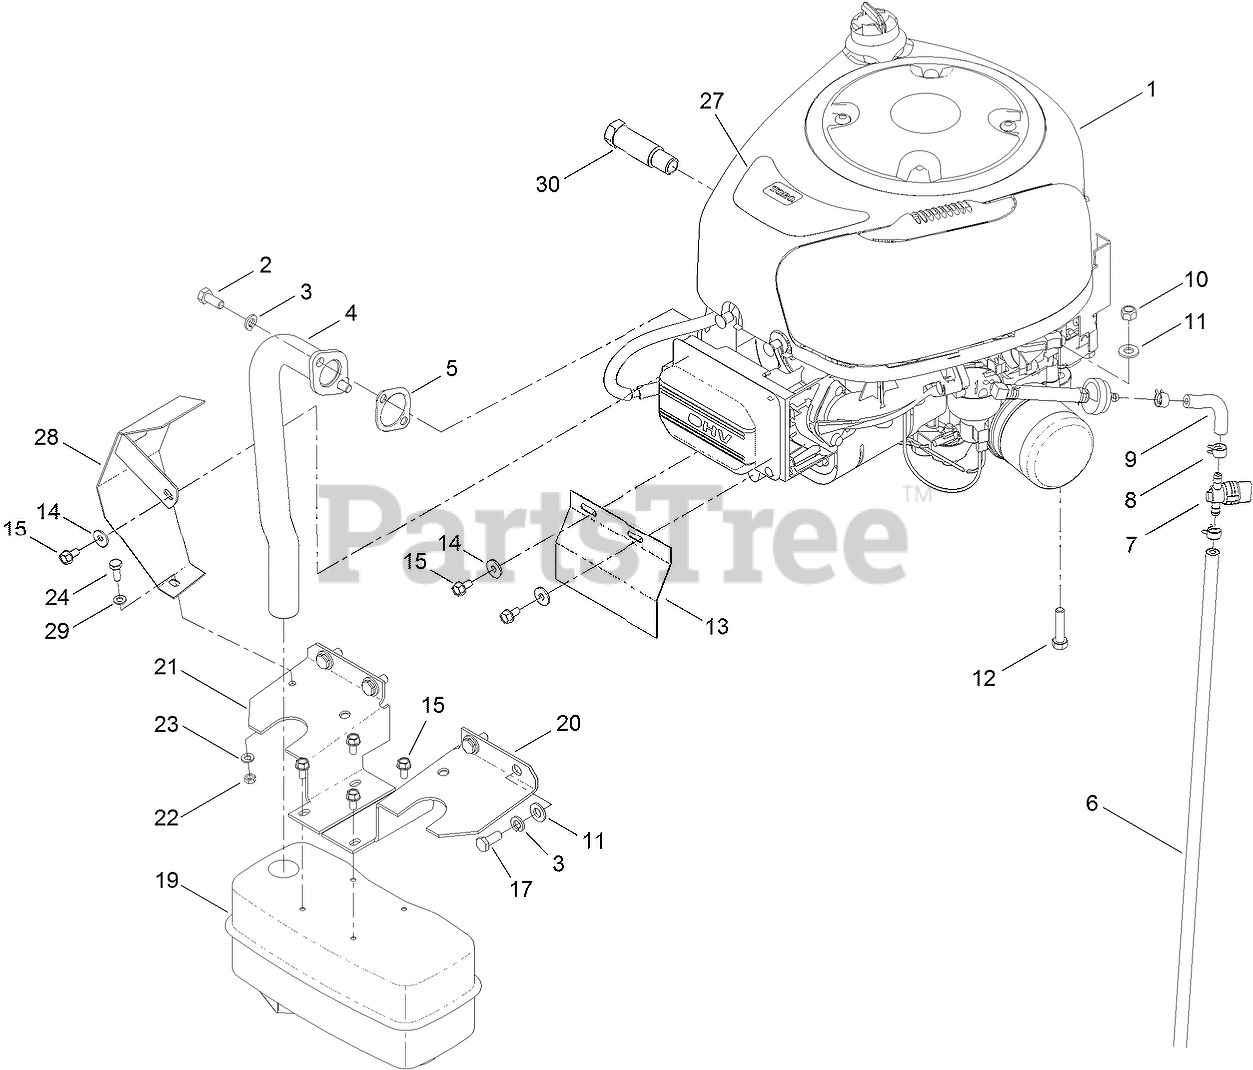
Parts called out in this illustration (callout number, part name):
2	SCREW-HH
3	WASHER-LOCK, SPRING
4	TUBE-EXHAUST
5	GASKET-EXHAUST
6	LINE-FUEL
7	VALVE-TANK, FUEL
8	CLAMP-LINE, FUEL
9	LINE-FUEL
10	NUT-LOCK, NI
11	WASHER-PLAIN
12	SCREW-HH
13	COVER-FRONT
14	WASHER-FLAT
17	SCREW-HH
19	MUFFLER
20	GUARD-MUFFLER, LH
21	GUARD-MUFFLER, RH
22	NUT-HEX
23	WASHER-SPRING
24	SCREW-HH
27	DECAL-ENGINE
28	Cover-Manifold, Exhaust
29	WASHER-FLAT
30	COUPLER-DRAIN, OIL
